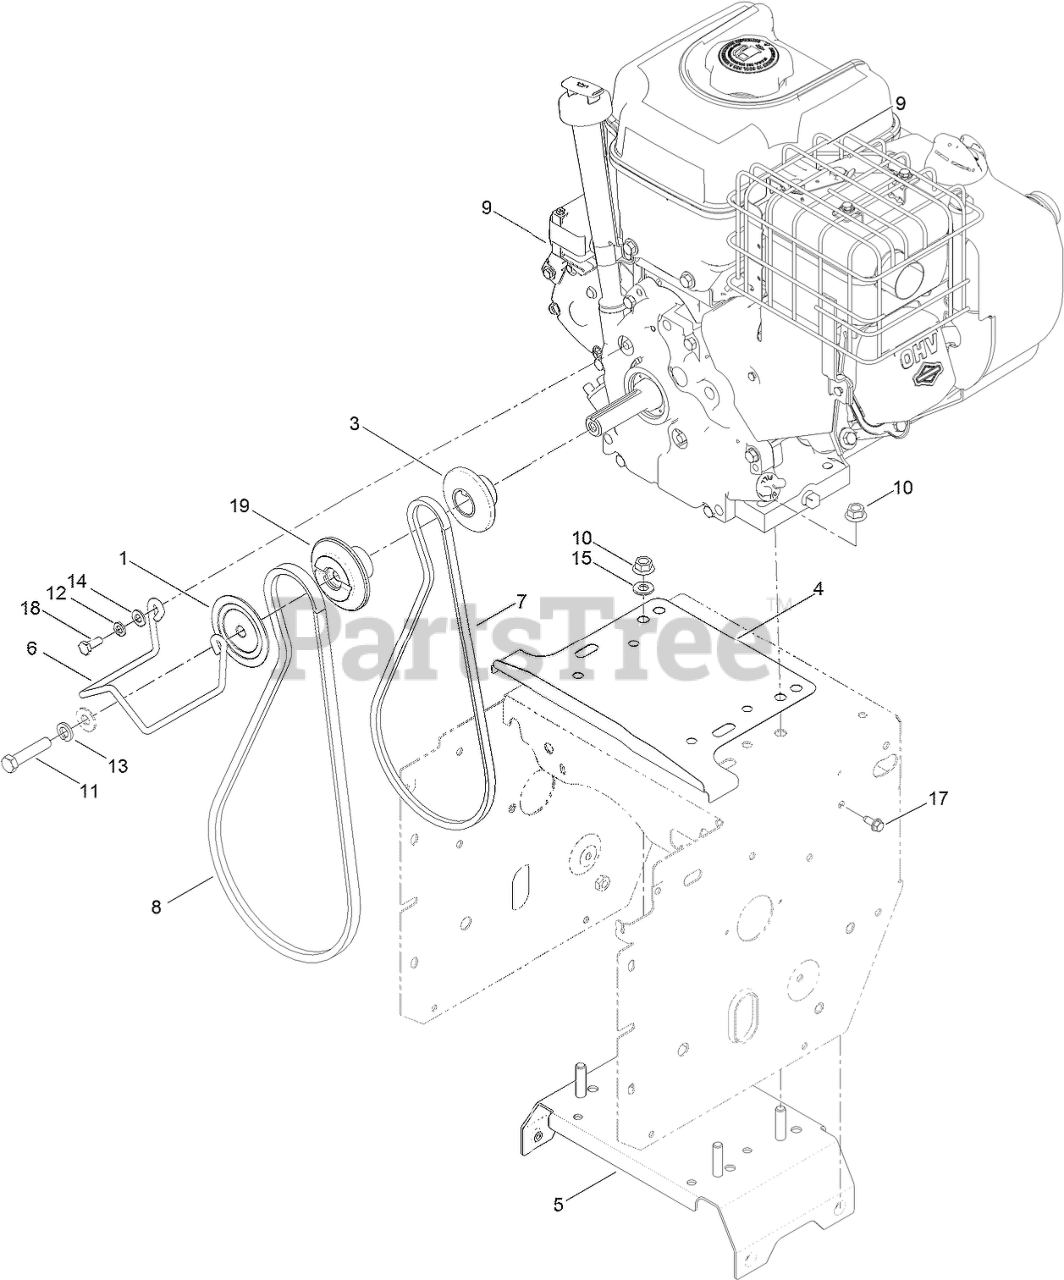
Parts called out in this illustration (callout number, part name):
1	SHEAVE-HALF, IMPELLER
3	SHEAVE-HALF, TRACTION
4	SHIELD-DRIVE
5	FRAME BRACE ASM
6	GUIDE-BELT
7	V BELT-TRACTION
8	BELT-V
10	NUT-HF
11	SCREW-HH
12	WASHER-LOCK
13	WASHER-LOCK
14	WASHER-PLAIN
15	WASHER-FLAT
17	SCREW-HWH
18	SCREW-HH
19	PULLEY-ENGINE, CENTER
